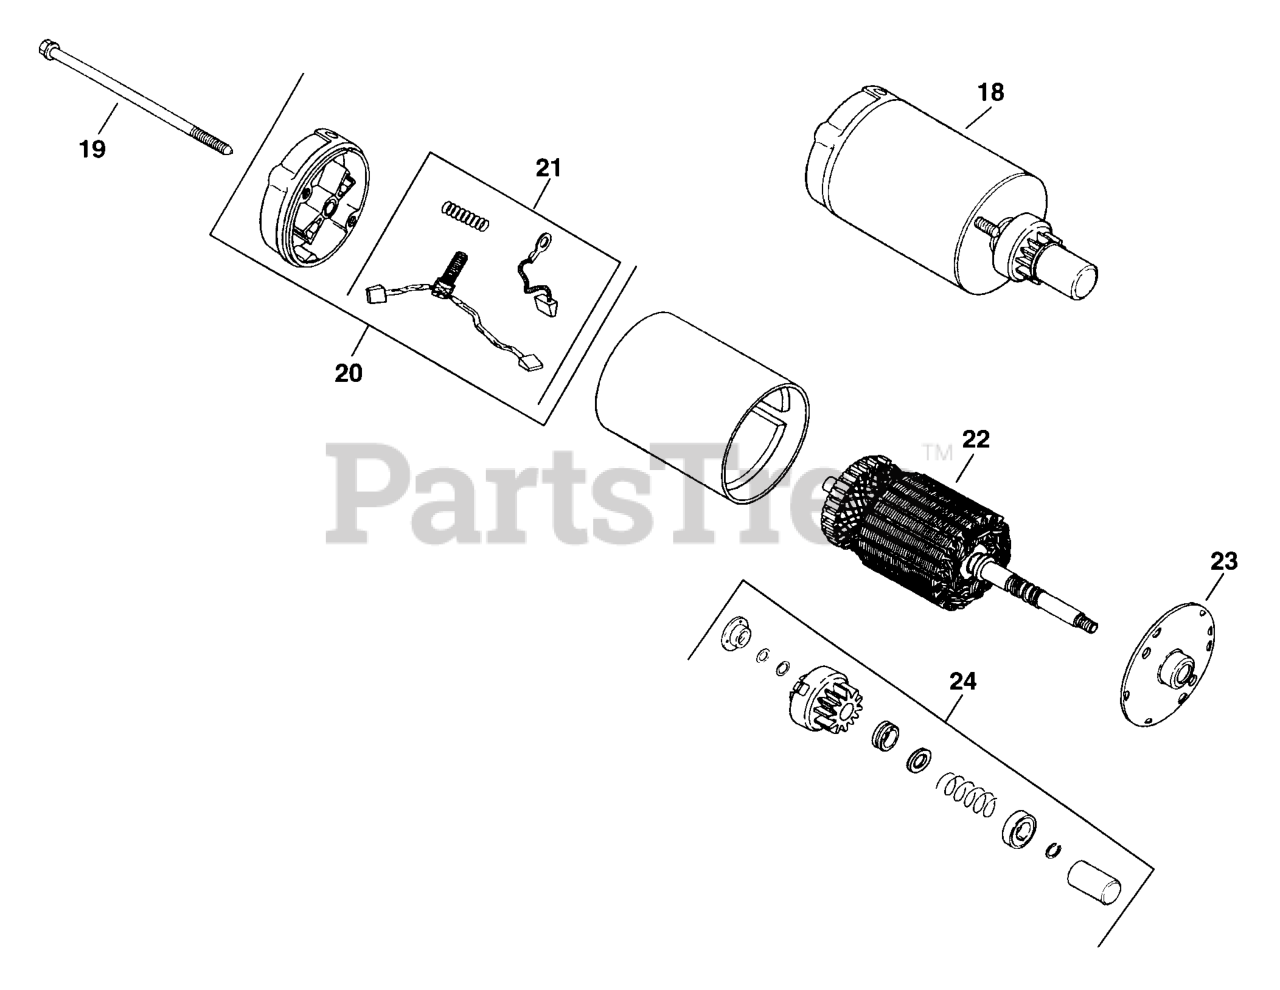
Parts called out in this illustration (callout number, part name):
18	ELECTRIC STARTER-BENDIX DRIVE
19	BOLT, STARTER 1/4-20X5-1/16"-(#DSC)
20	CAP ASSY, COMMUTATOR END - DISCONTINUED
21	KIT, BRUSH & SPRING - DISCONTINUED
22	ARMATURE ASSY - DISCONTINUED
23	HOUSING, DRIVE END CAP
24	KIT, DRIVE
5235701-S	Lubricant, Inertia Drive Starter (0.25 oz.)
